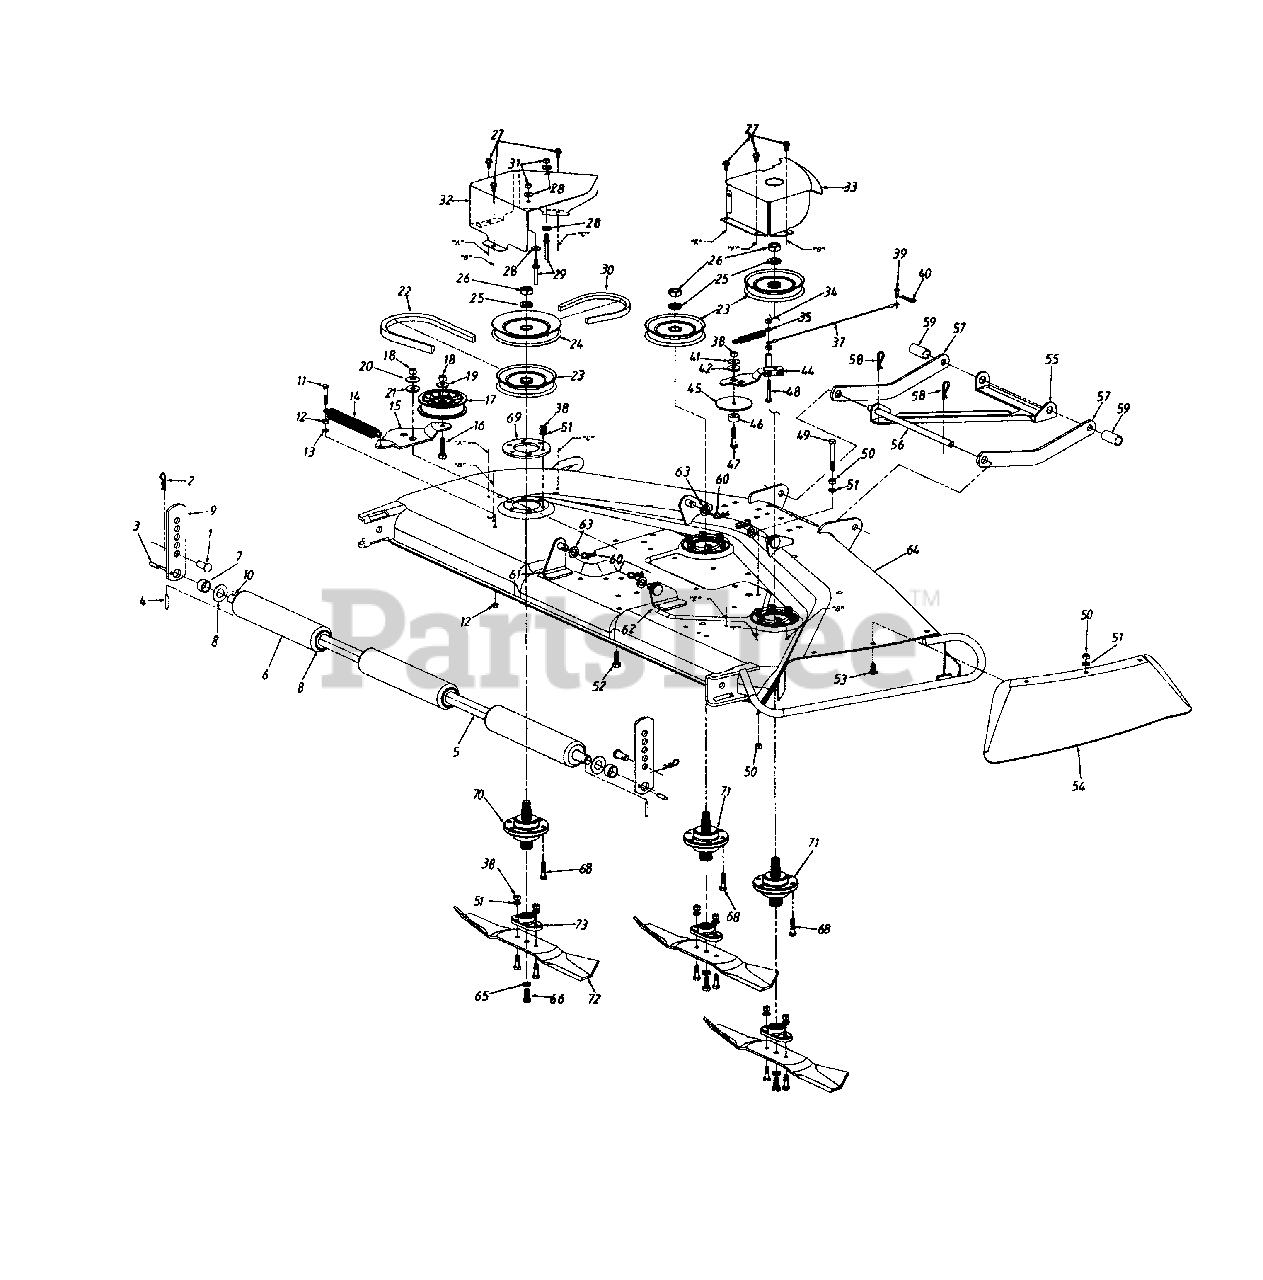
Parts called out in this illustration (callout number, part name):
1	Clevis Pin
2	Hairpin Clip
3	Spring Pin 1/4" x 1" Lg.
4	Spring Pin 3/16" x 1-1/4" Lg.
7	Spacer .75" I.D.
8	Fl-Wash..76" I.D. x 1.5" O.D.
10	Roller Shaft
11	Hex Bolt 1/4-28 x 1.5" Lg. (Gr. 5)
12	Hex Nut 1/4-28 Thd.
13	L-Wash. 1/4" I.D.
14	Ext. Spring 7.33" Lg.
17	Idler Pulley
18	Hex Nut 3/8-24 Thd.
19	Bell-Wash. 3/8" I.D.
20	Bell-Wash..39" I.D. x 1.13" O.D.
21	Shld. Spacer .625" I.D.
22	"V"-Belt
23	Deck Pulley
24	Upper Deck Pulley
25	L-Wash. 5/8" I.D.
26	Hex Jam Nut 5/8-18 Thd.
27	Hex Wash. Hd. Scr. 1/4-20 x .5" Lg.
28	Bell-Wash. 1/4" I.D.
29	Belt Guard Pin
30	"V"-Belt
31	Hex Nut 1/4-20 Thd.
35	Ext. Spring 3.97" Lg.
37	Brake Cable
38	Hex Nut 5/16-24 Thd.
39	Clevis Pin
40	Hairpin Clip
41	Bell-Wash..325" I.D.
42	Shld. Spacer
44	Brake Ass'y.
45	Fl-Wash. 5/16" I.D. x .3" O,D.
46	Spacer.44" Lg.
47	Hex Bolt 5/16-24 x 1.5" Lg. (Gr. 5)
48	Hex Bolt 1/4-28 x 1.75" Lg. (Gr. 5)
49	Hex Bolt 5/16-18 x 2.5" Lg.
50	Hex Nut 5/16-18 Thd.
51	L-Wash. 5/16" I.D.
52	Hex Bolt 3/8-24 x 1" Lg.
53	Carr. Bolt 5/16-18 x .75" Lg.
59	Spacer 1.75" Lg.
60	Hairpin Clip
63	Fl-Wash, 1/2" I.D. x .93" O.D.
66	Hex Bolt 3/8-24 x .88" Lg. (Gr. 5)
68	Hex Bolt 5/16-24 x 1-1/4" Lg.(Gr. 5)
69	Spindle Reinforcement Plate
70	Spindle Ass'y. (L.H.)
71	Spindle Ass'y. (R.H. & Center)
72	Blade
73	Blade Adapter
12649-0638	GUARD-CHUTE - MTD/TROY-BILT RED (0638)
12649-0648	GUARD-CHUTE - TECH GRAY (0648)
12650-4008	Height Adjuster - WINE RED (4008)
